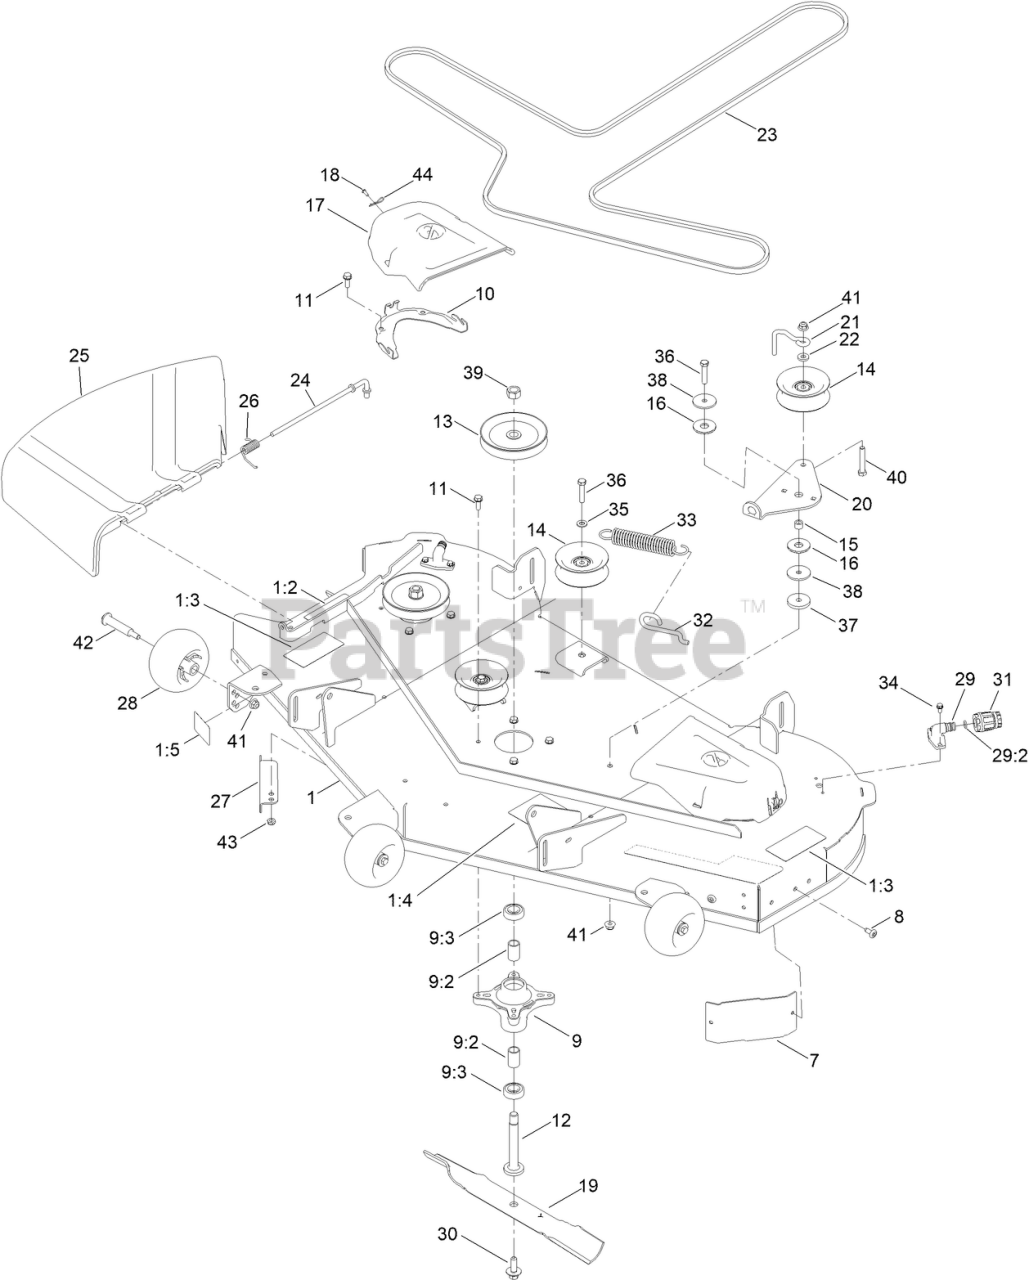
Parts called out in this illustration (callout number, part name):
1	54 IN DECK DECAL ASM
1:2	DECAL-DANGER DEFLECTOR [BLK-TXT]
1:3	DECAL-DANGER, DECK
1:4	DECAL-ROUTING, BELT
1:5	DECAL-SCALP, ANTI
7	BAFFLE-CORNER
9	SPINDLE ASM
9:2	SPACER
9:3	BEARING-BALL
10	BRACKET-COVER, BELT
11	SCREW-TAPTITE
12	SHAFT-SPINDLE
13	PULLEY ASM
14	PULLEY-IDLER, FLAT
15	SPACER
16	WASHER-FRICTION, COMPOSITE
17	COVER-BELT
18	SCREW
19	BLADE-HI LIFT
20	ARM-IDLER
21	BELT GUIDE - IDLER
22	SPACER-HUB, BLOWER
23	BELT-V (A SEC, 145.5 EL)
24	ROD-PIVOT
25	DEFLECTOR-DISCHARGE
26	SPRING-TORSION
27	BAFFLE-CUTOFF
28	ROLLER-SCALP, ANTI
29	FITTING-WASHOUT
29:2	O-RING
30	BOLT-BLADE, SEMS
31	CONNECTOR-HOSE
32	HOOK-RETURN SPRING
33	SPRING-EXTENSION
34	SCREW-HWH
35	WASHER-FLAT
36	SCREW-HH
37	WASHER-PLAIN
38	WASHER-REBOUND
39	NUT-HEX
40	SCREW-HH
41	NUT-HF, NI
42	BOLT-SHOULDER
44	PIN-HAIR
